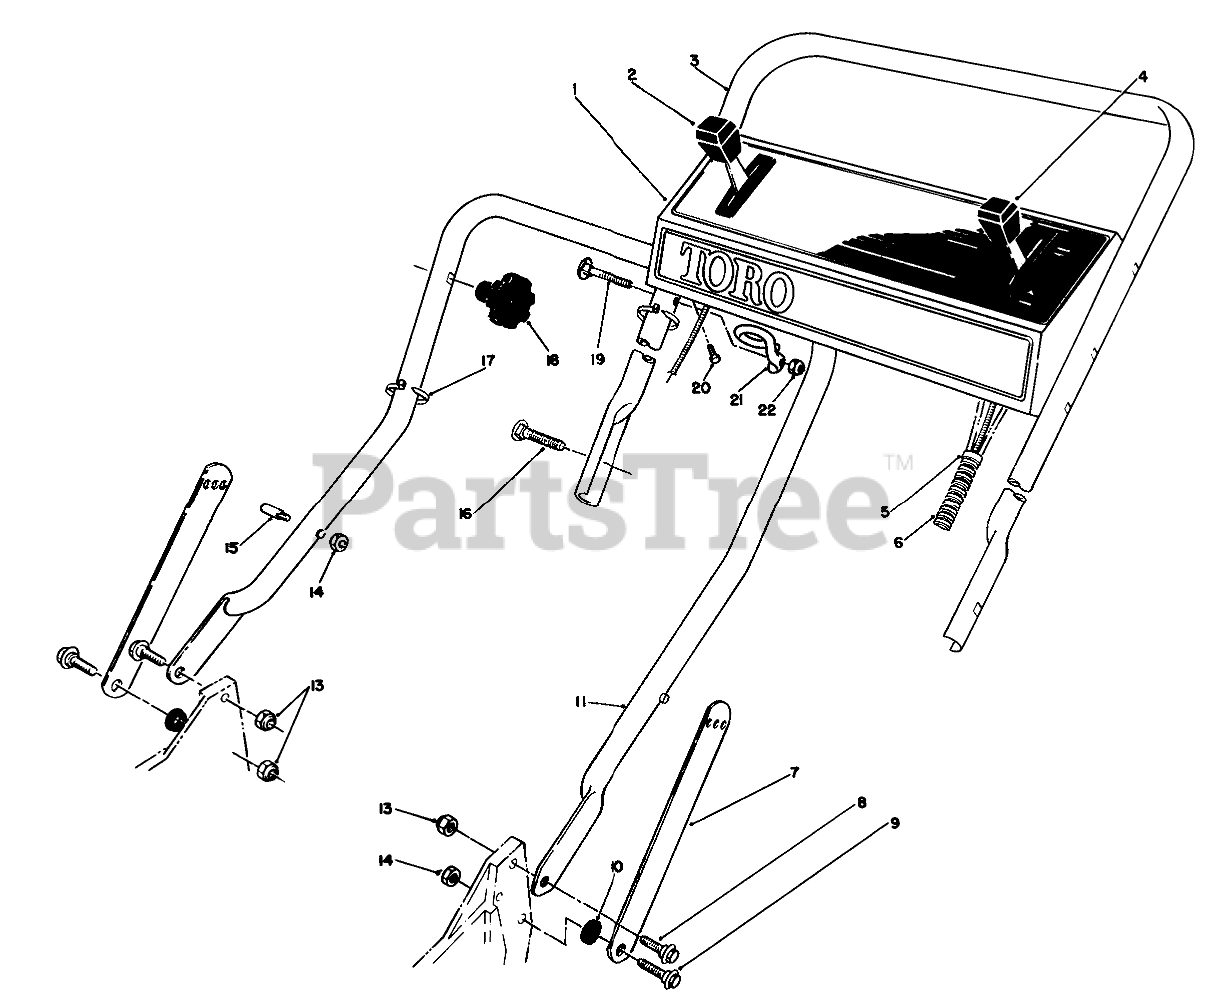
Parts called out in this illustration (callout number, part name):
1	CONTROL PANEL
2	GROUND SPEED CONTROL
3	UPPER HANDLE
4	THROTTLE CONTROL
5	FITTING-RING
6	CONTROL CABLE COVER
7	Handle Latch
8	SCREW-SHOULDER
9	SCREW-SHOULDER
10	SPACER
11	LOWER HANDLE ASM
13	NUT-LOCK, NI
14	NUT-LOCK, NI
15	HANDLE PIN
16	5/16-18 X 2 HNDLE SCREW
17	TIE-CABLE
19	HANDLE SCREW
20	SCREW-HWHTF
21	Guide
22	NUT-LOCK, NI
